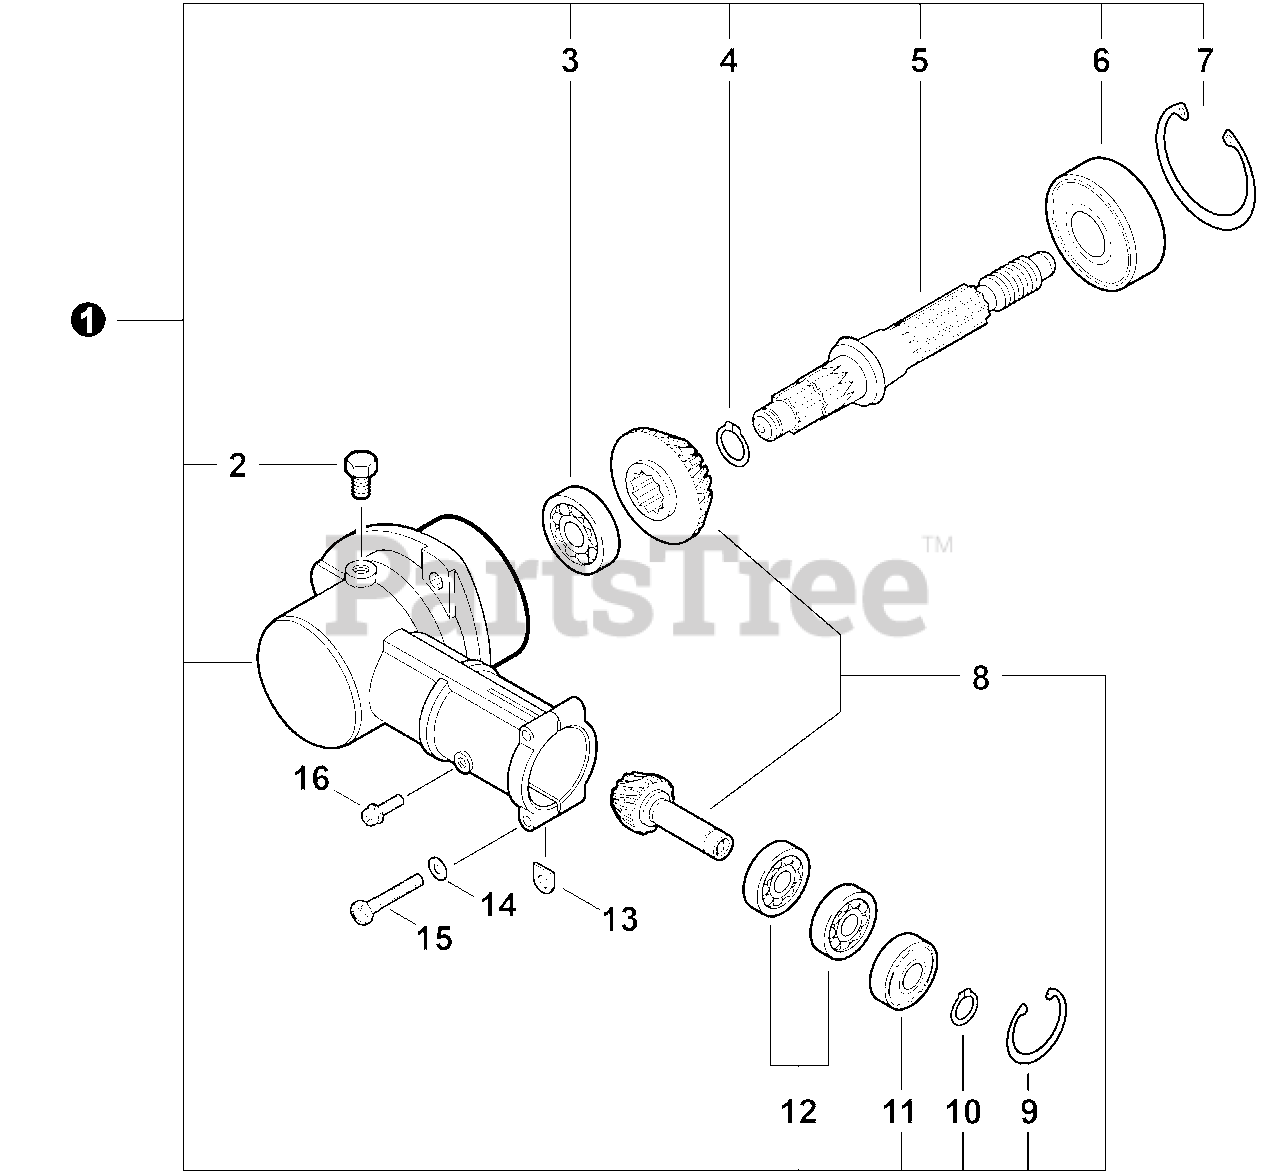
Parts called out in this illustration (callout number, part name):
1	GEAR CASE ASSY
2	BOLT M8×8
3	BEARING, BALL
4	RING, SNAP Ø12
5	SHAFT, GEAR
6	BEARING, BALL 6302
7	RING, SNAP Ø42
8	GEAR, BEVEL
9	RING, SNAP Ø22
10	RING, SNAP Ø10
11	BEARING, BALL 6900Z
12	BEARING, BALL 6900
14	WASHER, FLAT 5.5×10×0.8
15	BOLT 5×30
16	SCREW 5×12
